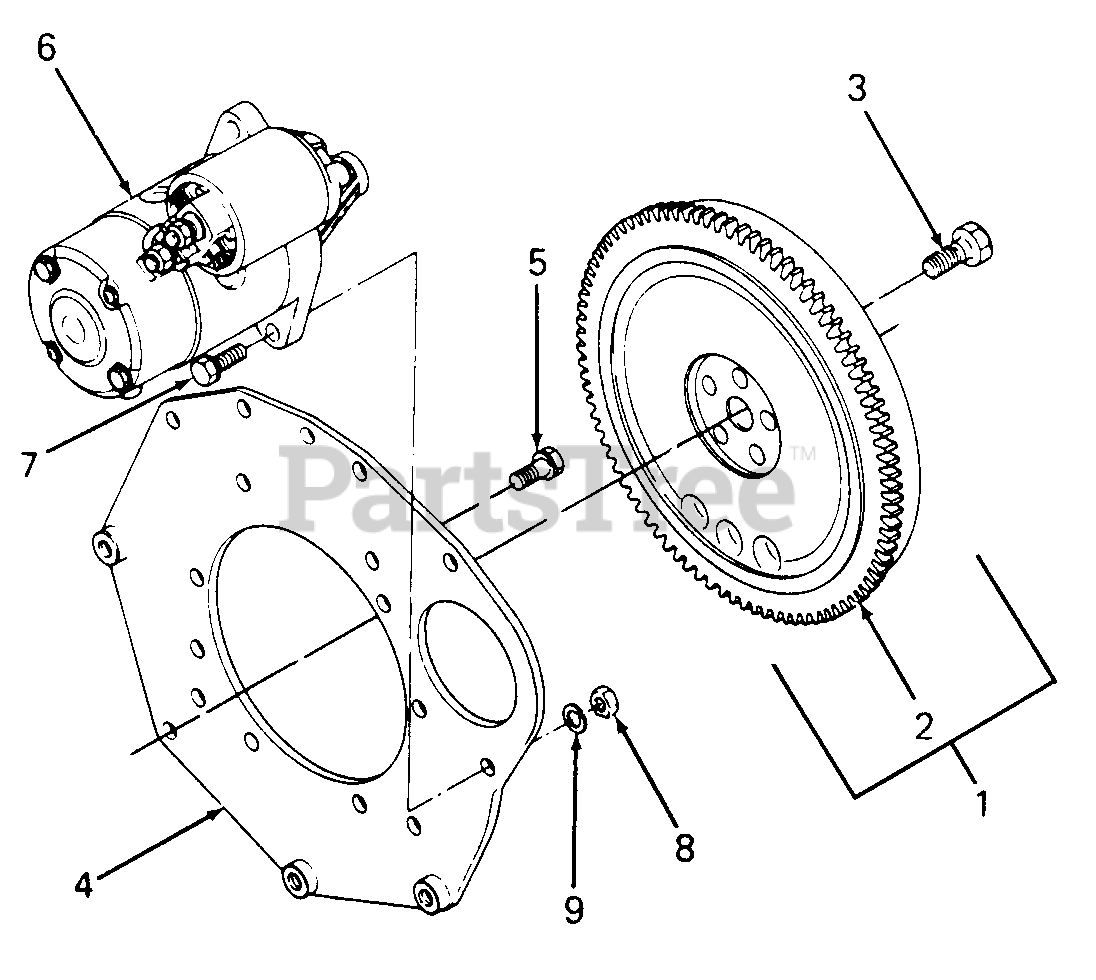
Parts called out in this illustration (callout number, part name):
1	Flywheel Assy
3	Bolt, Flywheel
4	Plate, Rear End
5	Screw, Hex Cap w/Washer
6	Starter
7	Screw, Hex Cap w/Washer
9	Washer, Lock
